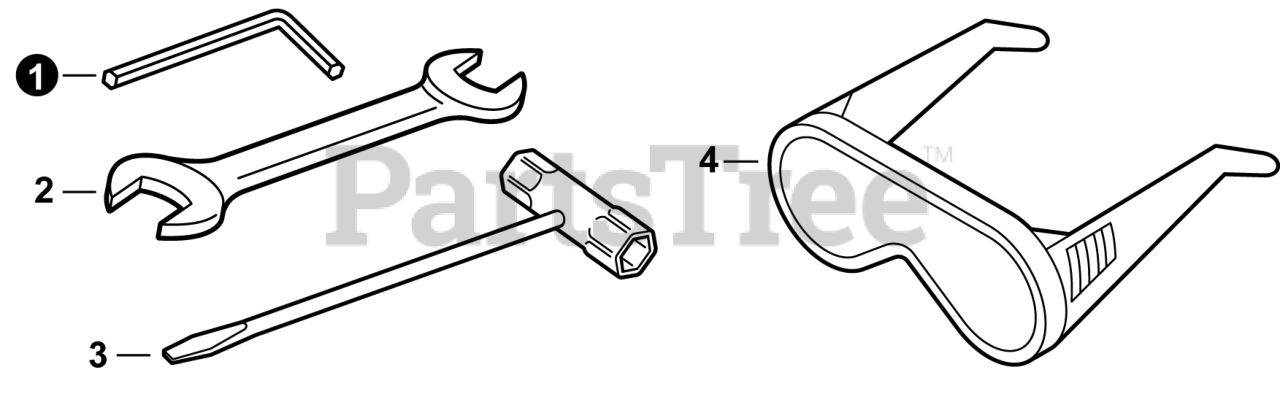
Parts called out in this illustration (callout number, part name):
1	WRENCH, ALLEN M5
2	SPANNER 8×10
3	T-WRENCH 17×19
4	GLASSES, SAFETY
